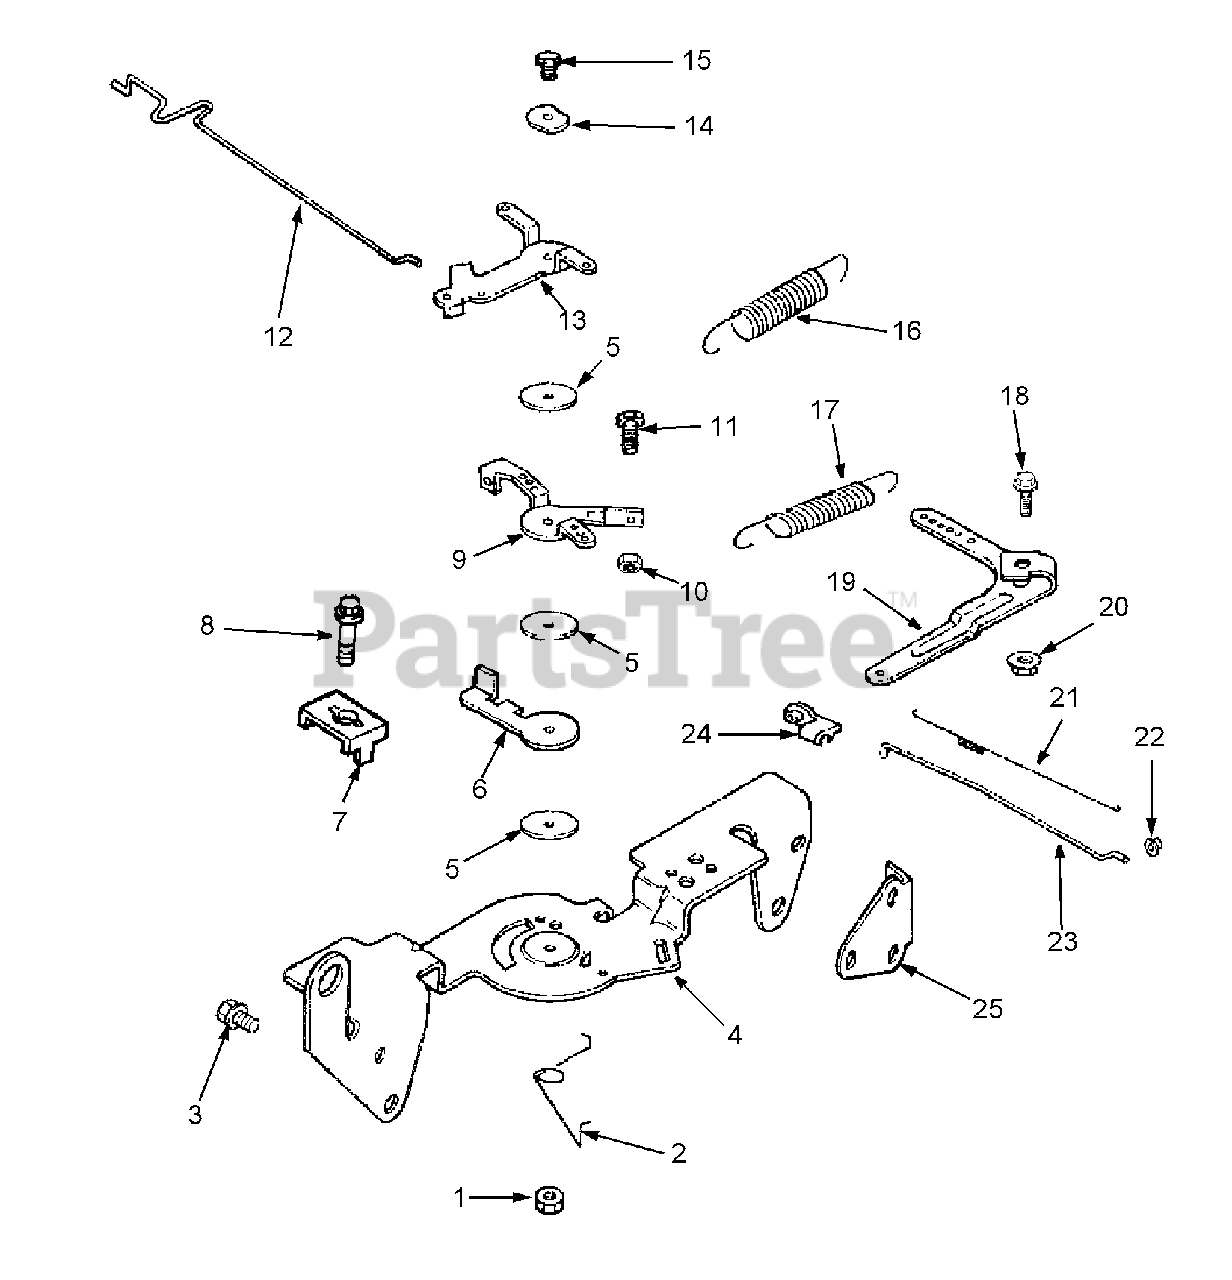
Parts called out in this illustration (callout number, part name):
1	Nut, Hex Lock M5 x 0.8
2	Spring, Choke Return
3	Screw, Hex Flange M6 x 1.0 x 16
4	Bracket, Control
5	Washer, Plain 5.5 mm
6	Lever, Throttle Actuator
7	Clamp,Cable,
8	Screw, Hex Flange M5 x 0.8 x 16
9	Lever, Throttle Control
10	Nut, Hex M4 x 0.7
11	Screw, Hex Cap M4 x 0.7 x 30
12	Linkage,Choke
13	Lever, Choke
14	Washer, Spring 1/4"
15	Screw, Hex Flange M5 x 0.8 x 20
16	Spring, Throttle Limiter
17	Spring, Governor
18	Screw, Hex Flange M6 x1.0 x 25
19	Lever, Governor
20	Nut, Hex Flange M6 x 1.0"
21	Spring, Linkage
22	Bushing, Linkage Retaining
23	Linkage, Throttle
24	Bushing, Linkage Retaining
25	Bracket Support
